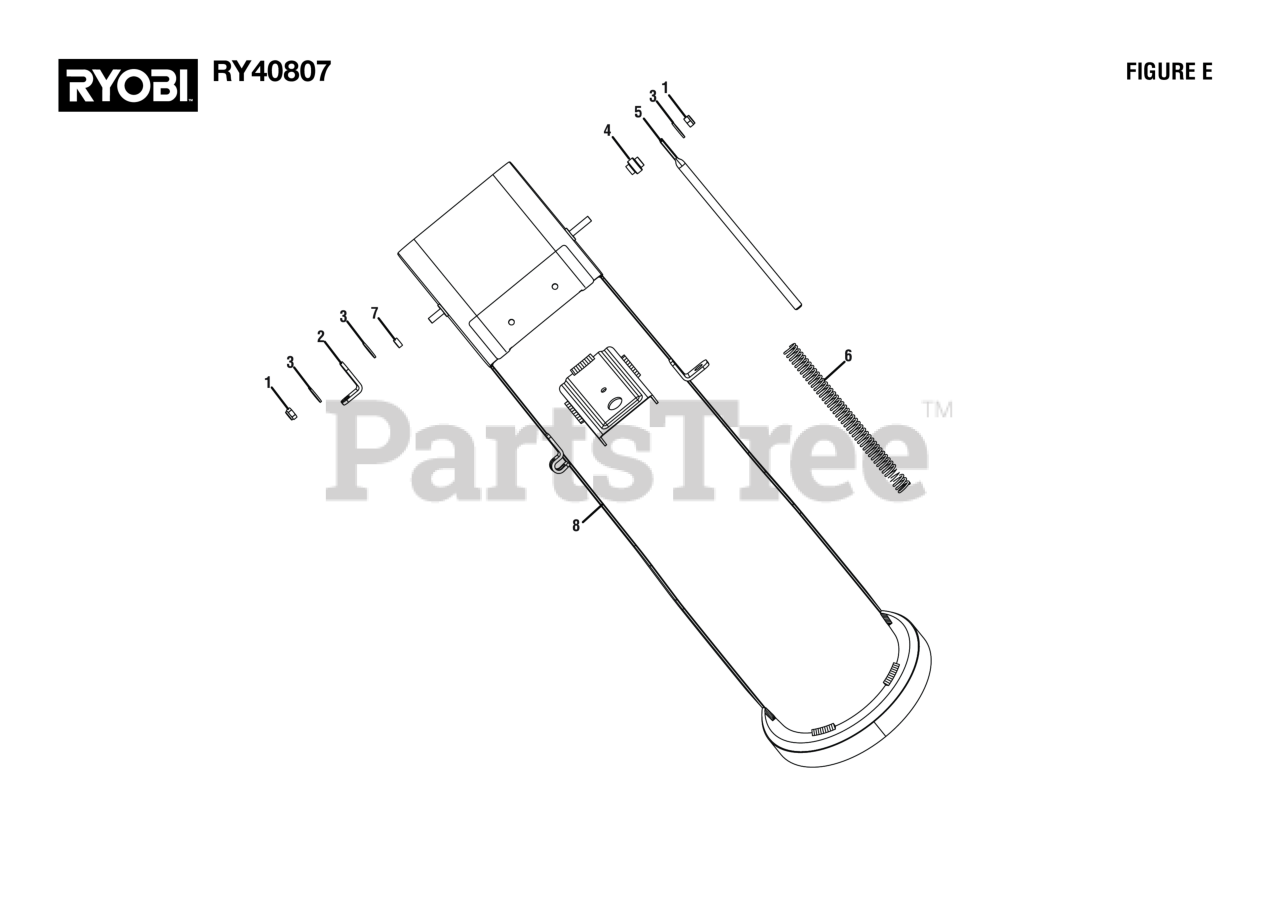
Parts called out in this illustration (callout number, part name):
1	Lock Nut (M6 x 6 mm)
2	Bracket Deflector
3	Washer (OD18 x ID6.5 x 1.5t)
4	Deflector Spring Spacer Bushing
5	Deflector Spring Guide
6	Deflector Spring
7	Deflector Bushing
8	Chute w/Label
